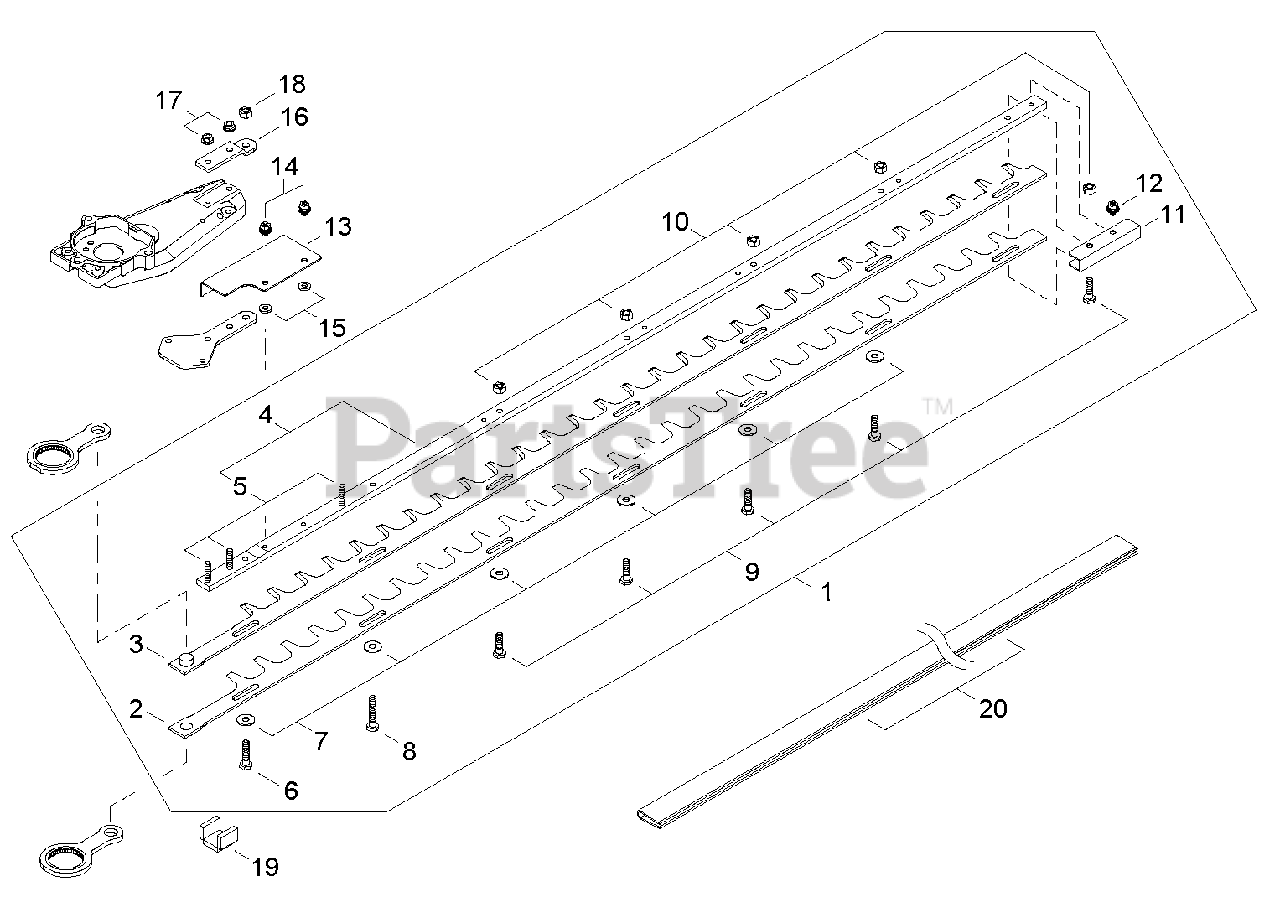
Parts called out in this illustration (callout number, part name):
1	CUTTER ASSY, 40"
2	BLADE, 40" CHROME LOWER
3	BLADE, 40" CHROME UPPER
4	GUIDE BAR ASSY, 40"
5	SCREW 5×25 SUS
7	WASHER M6
8	BOLT M6×32
9	BOLT M6×20
11	PLATE, GUIDE
12	BOLT M5×8
13	PROTECTOR
14	BOLT M5×8
15	WASHER 5
16	BRACKET, CUTTER
17	NUT, FLANGE M5
19	PACKING, FELT
20	SCABBARD 40"
